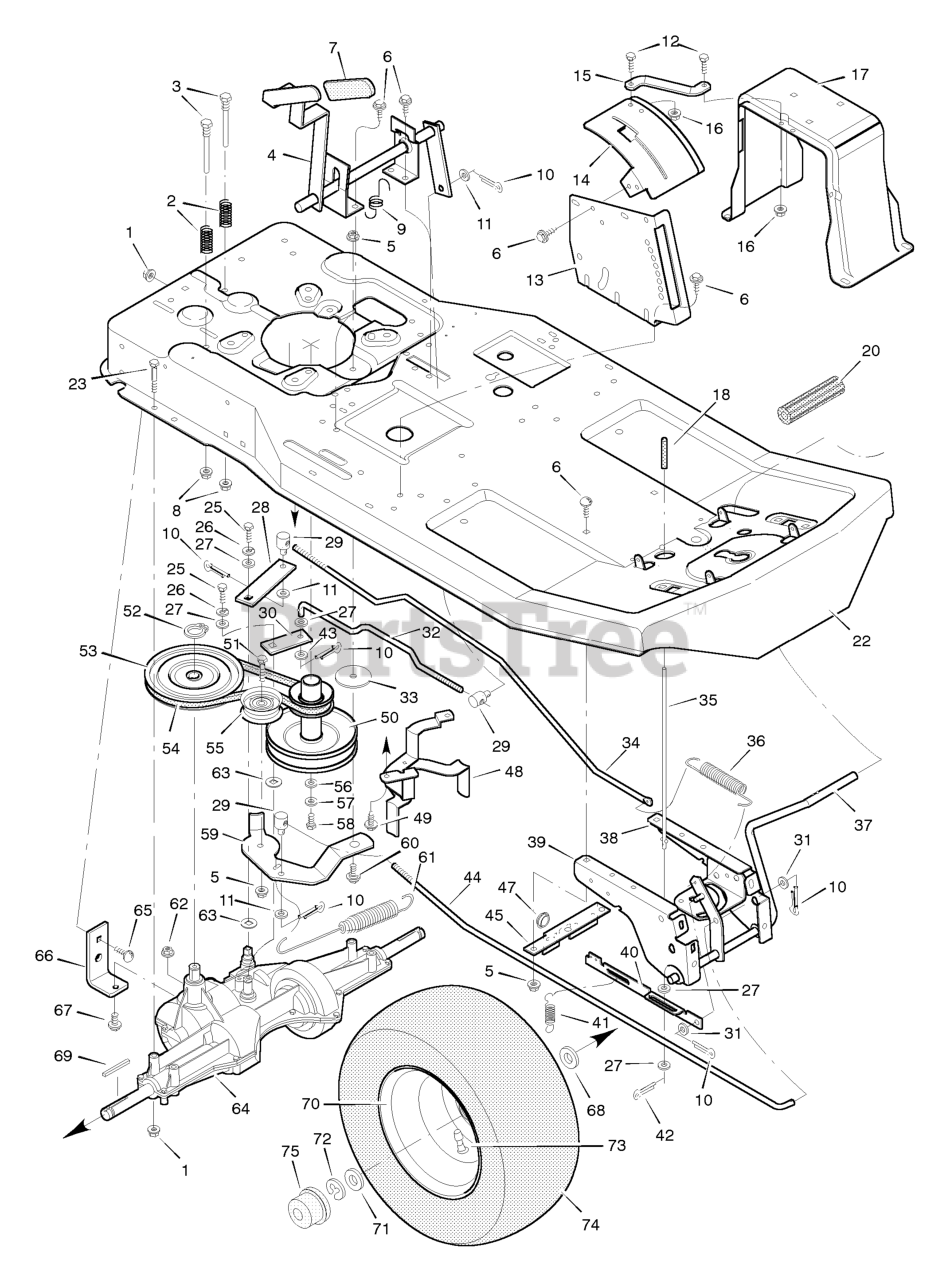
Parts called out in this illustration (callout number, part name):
1	Locknut, Flange
2	Spring, Compression
3	Guide, Belt
4	Shifter Assembly
5	Locknut, Flange
7	Grip, Shift Lever
8	Hex Nut
9	Spring, Extension
10	Pin, Cotter
11	Washer
12	Bolt, Hex
13	Plate, Index
14	Gate, Shift
15	Brace, Shift Gate
16	Locknut, Flange
17	Support, Seat
18	Grip, Parking Brake
20	Pedal, Rubber
22	Frame Assembly
23	Bolt, Hex
25	Bolt, Hex
26	Lockwasher
27	Washer
28	Yoke, Brake
29	Nut, Adjusting
30	Yoke, Shift
31	Washer
32	Rod, Shift
33	Washer, Hardened
34	Rod, Brake
35	Rod, Parking Brake
36	Spring, Extension
37	Lever, Pedal
38	Plate, Left Suspension
39	Plate, Right Suspension
40	Link, Parking Brake
41	Spring, Extension
42	Pin, Cotter
43	Washer
44	Rod, Clutch
45	Stop, Parking Brake
47	Grommet
48	Guide, Belt
50	Pulley Assembly, Stack
51	Bolt, Hex
52	Ring, Retainer
53	Pulley, Drive
54	Belt, Motion Drive
55	Pulley, Idler
57	Lockwasher
58	Bolt, Hex
59	Bracket, Idler
60	Bolt, Shoulder
61	Spring, Extension
62	Locknut, Hex
64	Transaxle, Dana Model 4450-1 **
65	Bolt, Carriage
66	Bracket, Transaxle
67	Bolt, Hex
69	Key, Square
70	Wheel & Tire Assembly
73	Valve Stem
74	Tire *
75	Hub Cap
